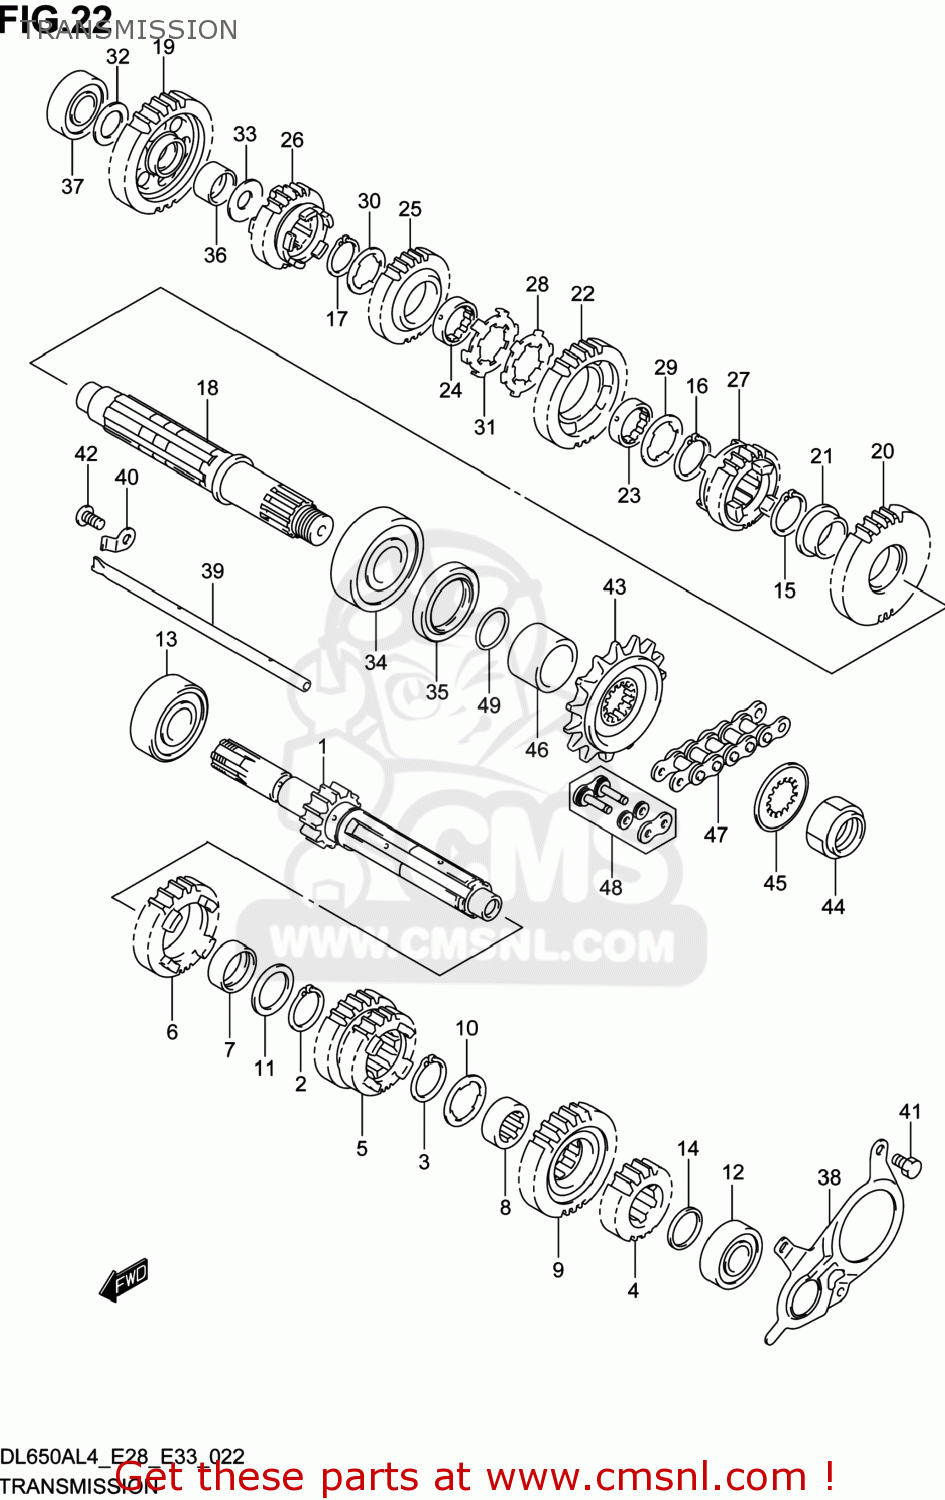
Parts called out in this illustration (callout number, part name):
1	SHAFT,COUNTER
2	CIRCLIP
3	CIRCLIP
4	GEAR,2ND DRIVE
5	GEAR,3RD & 4TH DRIVE
6	GEAR,5TH DRIVE(NT:26)
7	BUSH
8	BUSH,6TH DRIVE GEAR
9	GEAR,6TH DRIVE(NT:27)
10	WASHER,LOCK
11	SHIM(25X34X1)
12	BEARING(17X40X12)
13	BEARING(20X52X15)
14	CIRCLIP
15	CIRCLIP
16	CIRCLIP
17	CIRCLIP
18	SHAFT,DRIVE
19	GEAR,1ST DRIVEN
20	GEAR,2ND DRIVEN
21	BUSH,2ND DRIVEN GEAR
22	GEAR,3RD DRIVEN
23	BUSH,DRIVEN GEAR
24	BUSH,DRIVEN GEAR
25	GEAR,4TH DRIVEN
26	GEAR,5TH DRIVEN
27	GEAR,6TH DRIVEN
28	WASHER,LOCK
29	WASHER,LOCK
30	WASHER,LOCK
31	WASHER
32	SHIM(17X28X1)
33	SHIM(20X30X1)
34	BEARING(25X62X17)
35	SEAL,OIL(36X50X6)
36	BUSH(20X24X13)
37	BEARING(17X40X12)
38	RETAINER,DRIVE SHAFT OIL SEAL
39	GUIDE,T/M OIL
40	RETAINER,TRANSMISSION OIL
41	BOLT
42	SCREW
43	SPROCKET,ENGINE(NT:15)
44	NUT
45	WASHER,LOCK
46	SPACER,ENGINE SPROCKET
47	CHAIN,DRIVE
48	JOINT SET,DRIVE CHAIN
49	O RING(D:2.4,ID:23.7)
